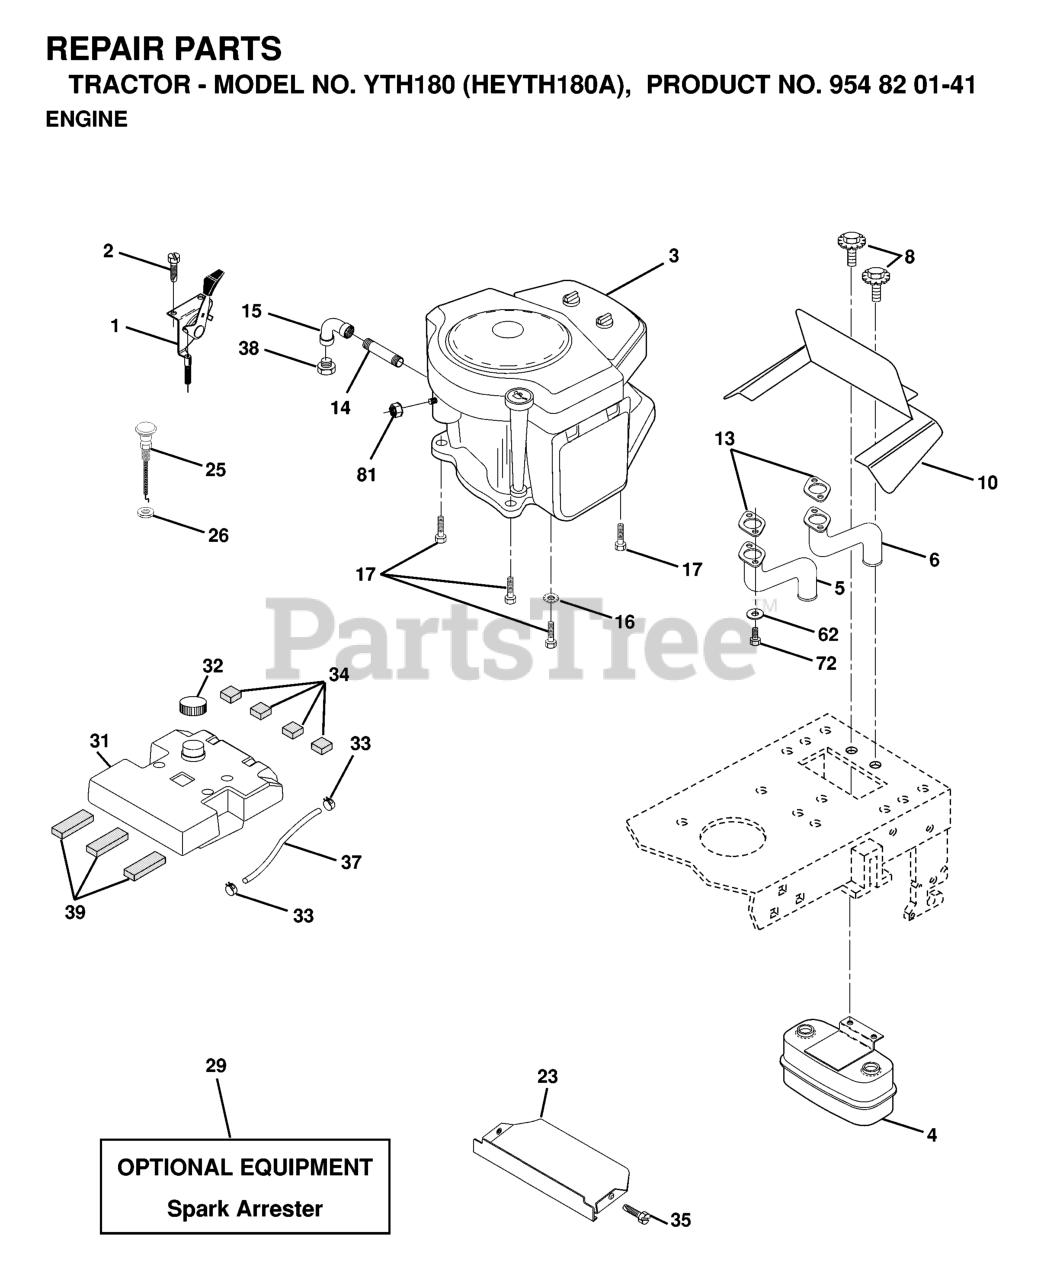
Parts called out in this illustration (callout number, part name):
1	CONTROL THROTTLE 36"
2	SCREW LT
4	MUFFLER.TWIN.CYL.LOW.TONE
5	RP.EXHAUST.TUBE.LH.BS/TWIN
6	EXHAUST.TUBE.RH.BS/TWIN
8	BOLT HEX WASHER HD 5/16-18
10	SHIELD.BROWNING.B&S
13	GASKET.MUFFLER
14	Nipple, Pipe 3/8 NPT x 4-1/2
15	ELBOW
16	LOCKWASHER
17	SCREW LT
25	CONTROL, CHOKE
26	Nut Keps 3/8 - 24 UNF
29	KIT.SPARK ARRESTOR 794945 B&S
31	TANK.FUEL(3.5.GAL)
32	FUEL CAP
33	HOSE CLAMP
34	PAD-SPACER LT
35	SCREW.THDROL.5/16-18X3/4.TTY
37	HOSE T
39	PAD IDLER TI
62	WASHER.LOCK.HVY.HLCL.SPR.5/16
72	SCREW
81	NUT FLANGE 1/4-20 STARTER NUT
